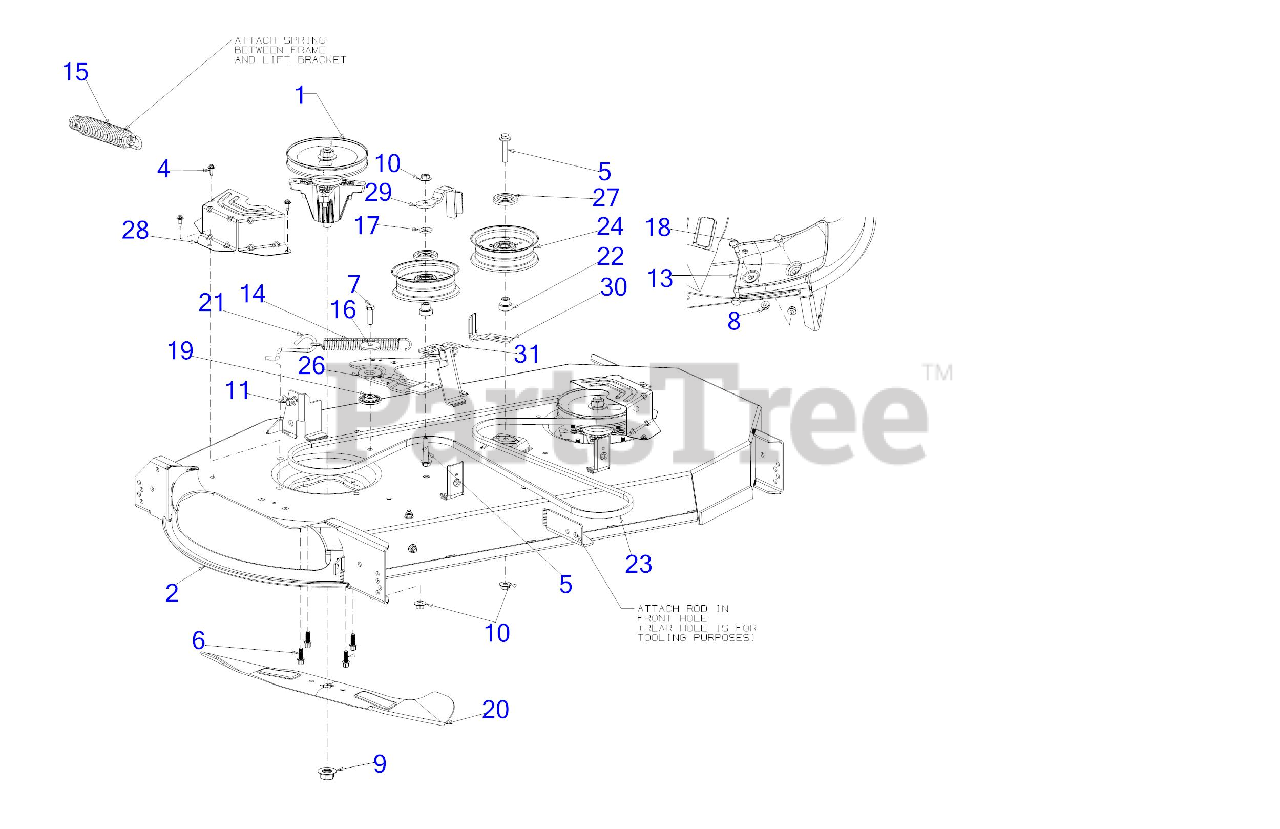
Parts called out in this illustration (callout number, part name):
1	PULLEY & SPINDLE ASSEMBLY
4	SCREW M6-1 x .625
5	SCREW 3/8-16 x 2.0
6	SCREW 5/16-18 X .875
7	SCREW 3/8-16 x 1.25 GR5
8	FLANGE LOCK NUT 5/16-18
10	FLANGE LOCK NUT
11	BOW TIE COTTER PIN
13	DISCHARGE BAFFLE
14	EXTENSION SPRING
15	LIFT ASSIST SPRING
16	FLAT WASHER .390x1.500x.134
17	FLAT WASHER .385 x 1.00 x .135
18	SHOULDER SCREW
19	SHOULDER SPACER
20	23.25" BLADE
21	DECK SPRING HOOK
22	SHOULDER SPACER
23	V-BELT A SEC X108.3LG 46FAB
24	IDLER PULLEY 4.50" DIA
27	IDLER PULLEY CAP
29	BELT KEEPER
